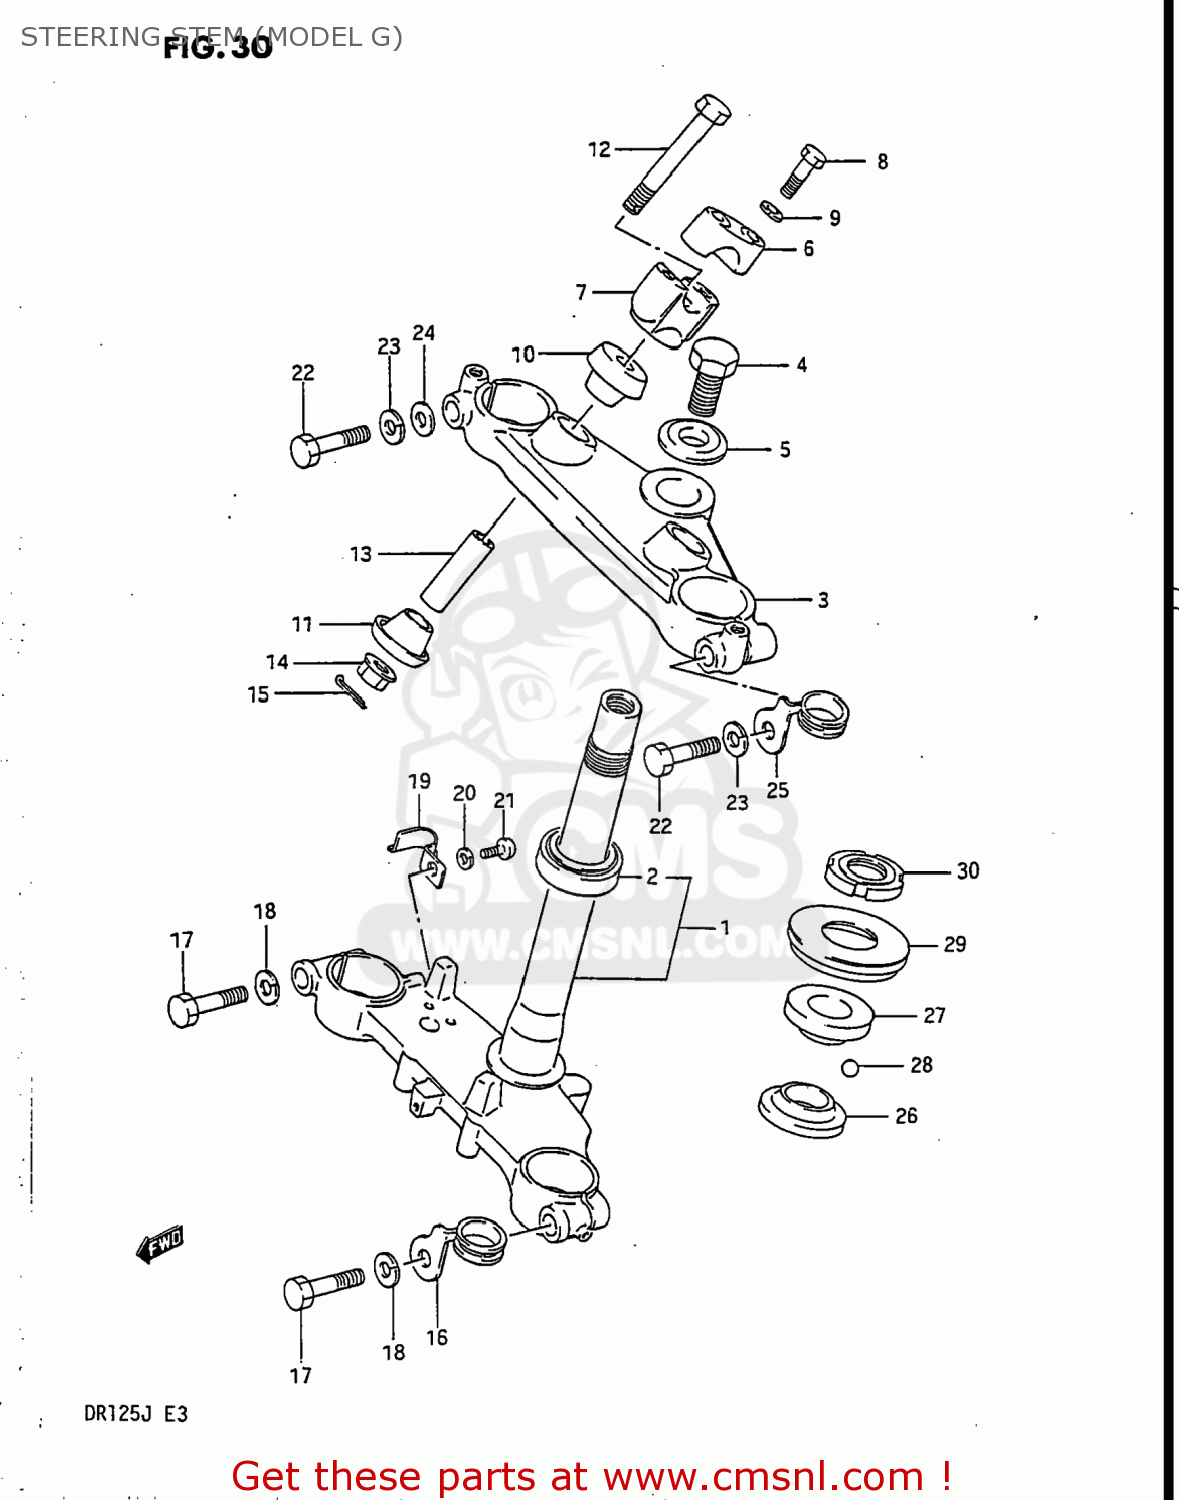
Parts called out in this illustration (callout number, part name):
1	STEM,STEERING
2	BEARING
3	HEAD,STEERING STEM
4	BOLT,STEERING STEM
5	WASHER
6	HOLDER,HANDLEBAR
7	HOLDER,HANDLEBAR,LOWER
8	BOLT
9	LOCK WASHER
10	CUSHION
11	RUBBER,LOWER
12	BOLT
13	SPACER
14	NUT
15	COTTER PIN
16	CLIP,UPPER
17	BOLT,FORK INNER TUBE FITTING
18	LOCK WASHER
19	CLIP
20	WASHER,LOCK
21	SCREW
22	BOLT,FORK INNER TUBE FITTING
23	LOCK WASHER
24	WASHER
25	CLIP,UPPER
26	RACE,STEERING,INNER,UPPER
27	RACE,STEERING,OUTER,UPPER
28	BALL
29	SEAL,STEERING UPR DUST
30	NUT,STEERING STEM
